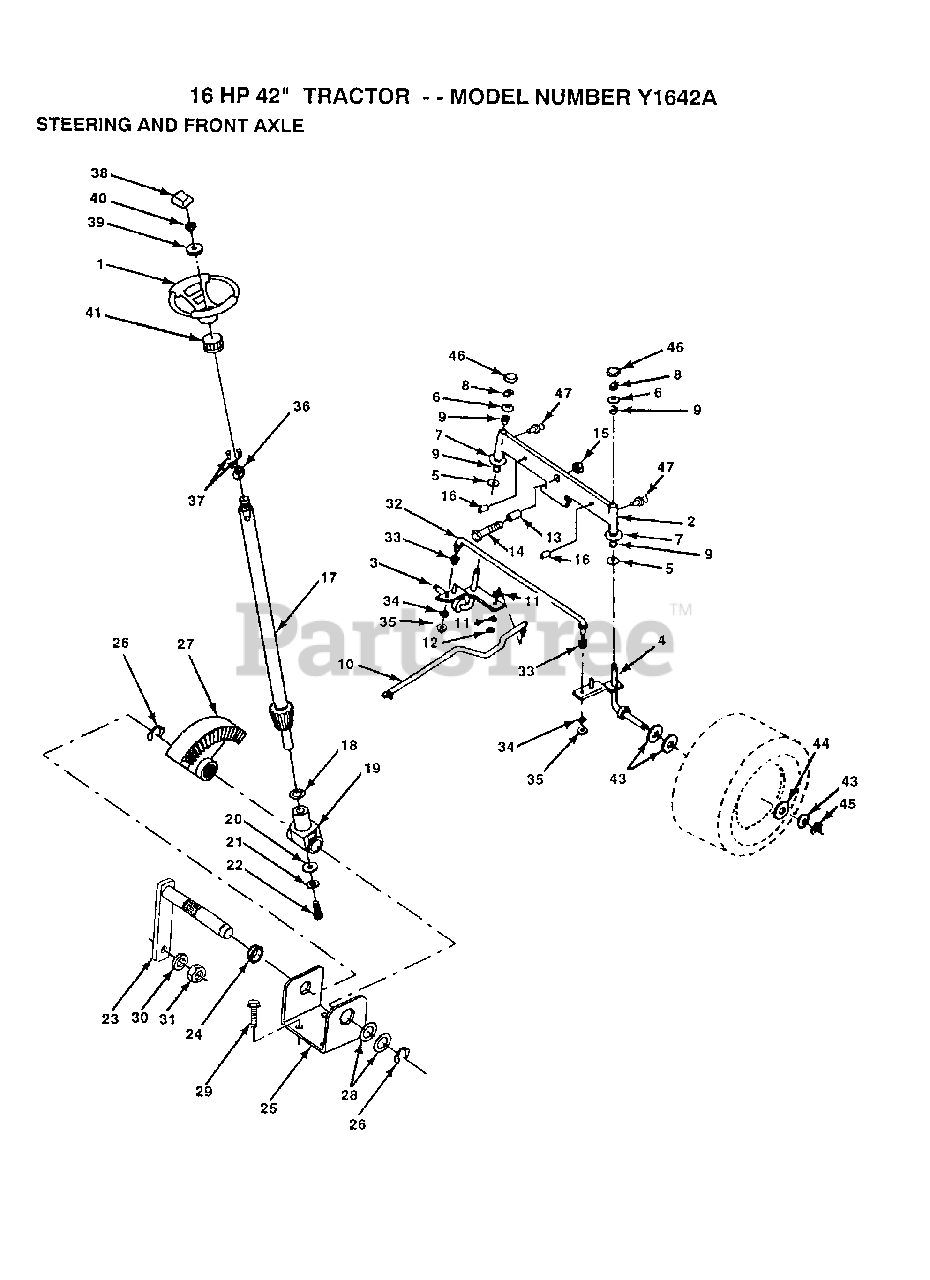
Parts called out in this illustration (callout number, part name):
3	SPINDLE LH
4	SPINDLE RH
5	WASHER .T
6	WASHER
7	WASHER
8	RING
9	COL. SRTG. BEAR.
11	LOCKWASHER
13	BEARING
14	BOLT HEX 5/8-11
16	AXLE PIN
17	STEERING SHAFT
18	THRUST WASHER
19	SUPPORT.SHAFT
21	LOCKWASHER
22	"SCREW,SPECIAL"
24	NYLINER T
25	"BRKT,STEERING"
26	RING
28	WASHER .T
29	SCREW
30	LOCKWASHER
32	TIE ROD
33	WASHER M
34	LOCKWASHER
35	NUT.LOCK.5/16-24
38	INSERT STEERING
39	WASHER
41	ADAPTER LT
43	WASHER
44	WASHER
45	RING
46	CAP
47	ZERK M
